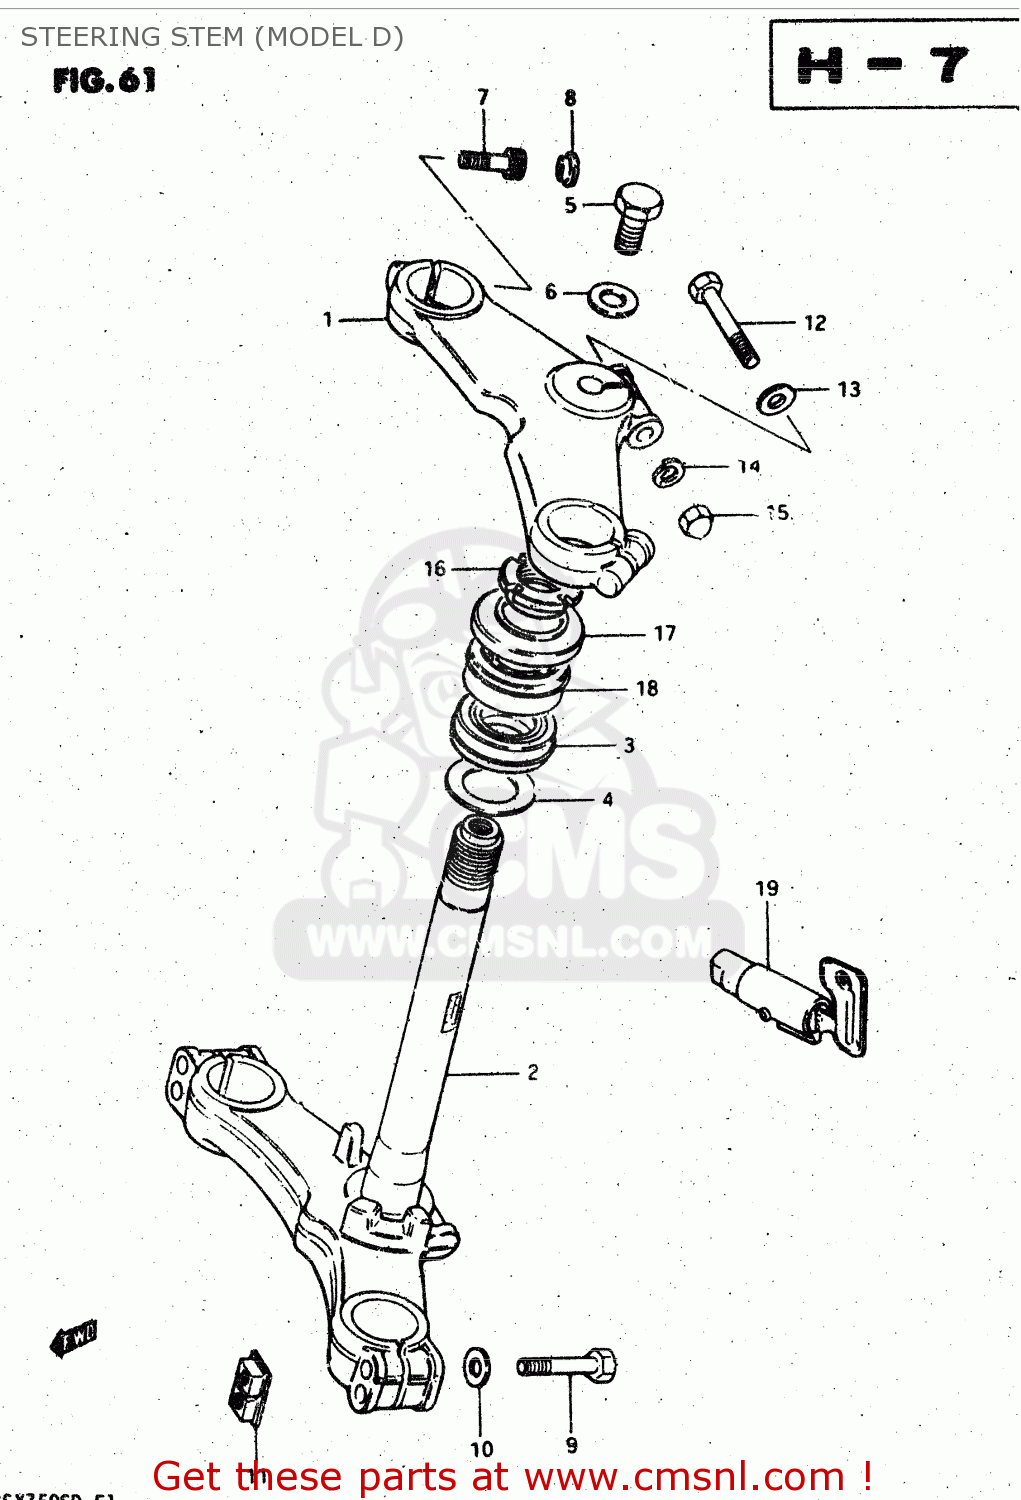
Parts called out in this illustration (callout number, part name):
1	HEAD,STEERING STEM
2	STEM,STEERING
3	BEARING
4	WASHER,THRUST
5	NUT,STEM HEAD
6	WASHER,STEERING STEM B
7	BOLT
8	CAP(OD:20)
9	BOLT 8X55
10	WASHER
11	NUT,FR FORK INNER TUBE
12	BOLT 8X50
13	WASHER
14	WASHER,LOCK,8.
15	NUT,M8X1.25X12
16	NUT,STEERING STEM
17	DUST SEAL,STEERING UPR
18	TAPER,ROLLER BEARING
19	LOCK ASSEMBLY,STEERING (NEI
